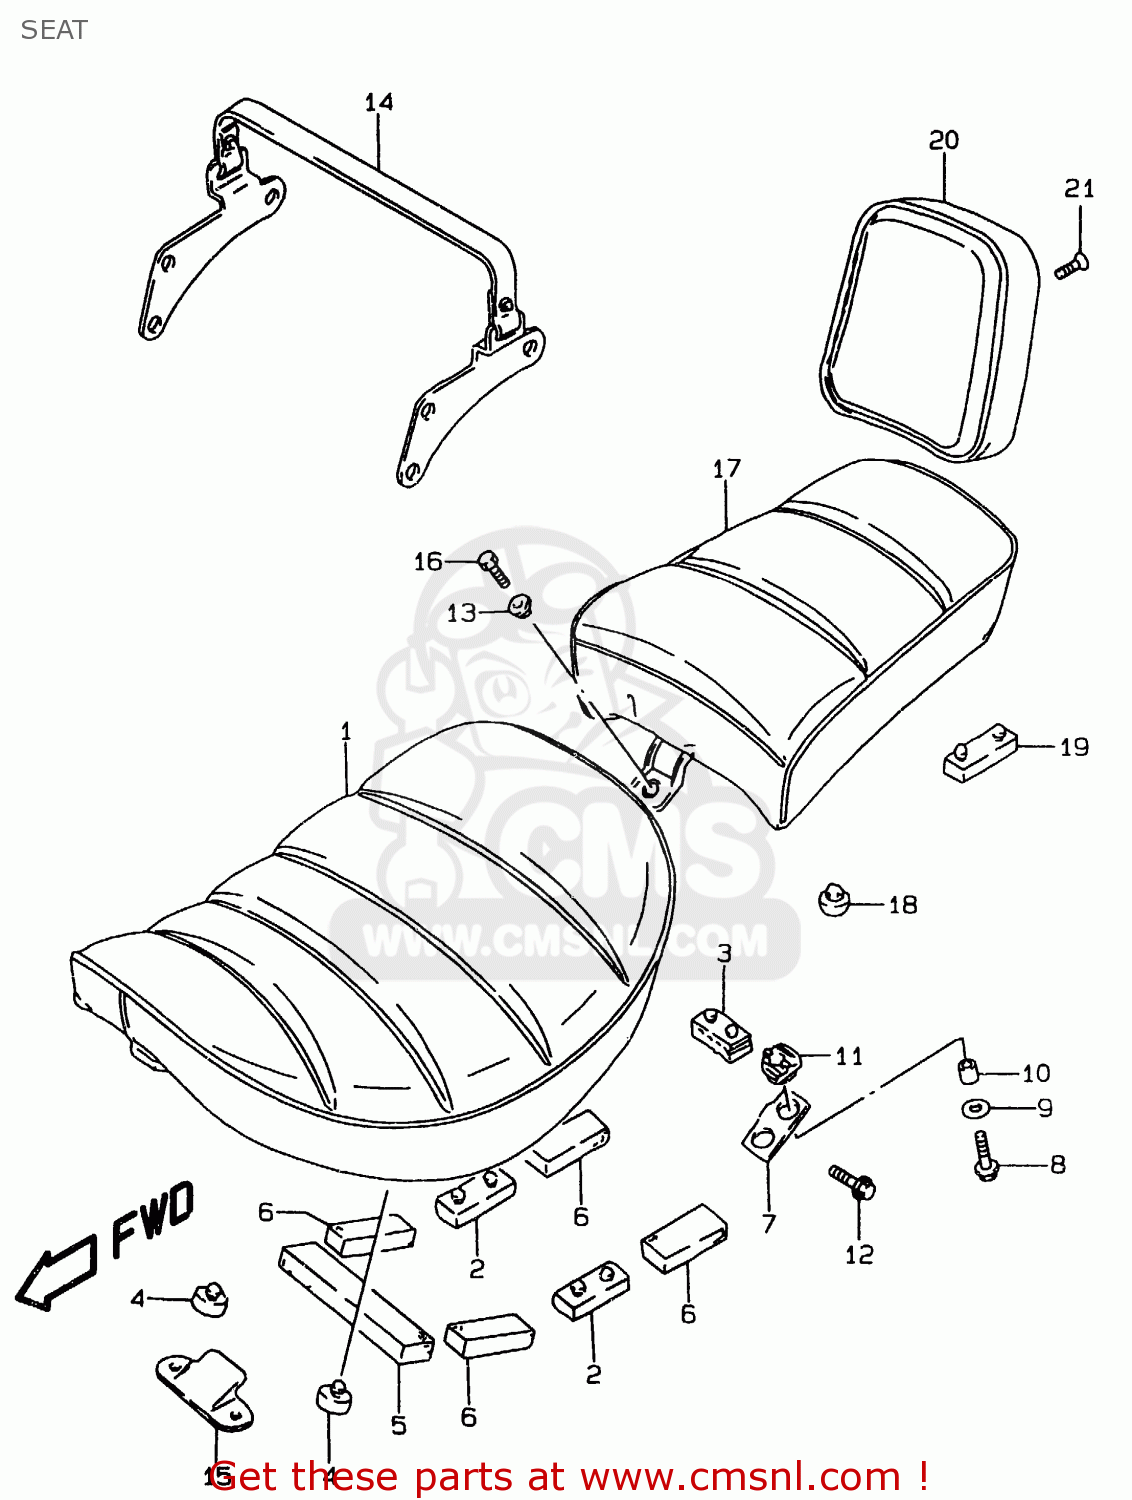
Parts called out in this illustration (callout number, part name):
1	SEAT SET
2	CUSHION,SEAT
3	CUSHION,SEAT(40X20X15)
4	CUSHION(11.5X22X20)
5	CUSHION,CTR FR
6	CUSHION,CTR SIDE
7	BRACKET,SEAT RR
8	BOLT
9	WASHER(6.5X20X1.6)
10	COLLAR,SEAT(TS-5A1-02273)
11	CUSHION,SEAT RR BRACKET
12	BOLT
13	WASHER
14	BAND,SEAT
15	PLATE,SEAT HOOK FR
16	BOLT
17	SEAT SET,PILLION
18	CUSHION,SEAT
19	CUSHION,SEAT
20	PAD ASSY,SEAT
21	SCREW,SUNVISOR
